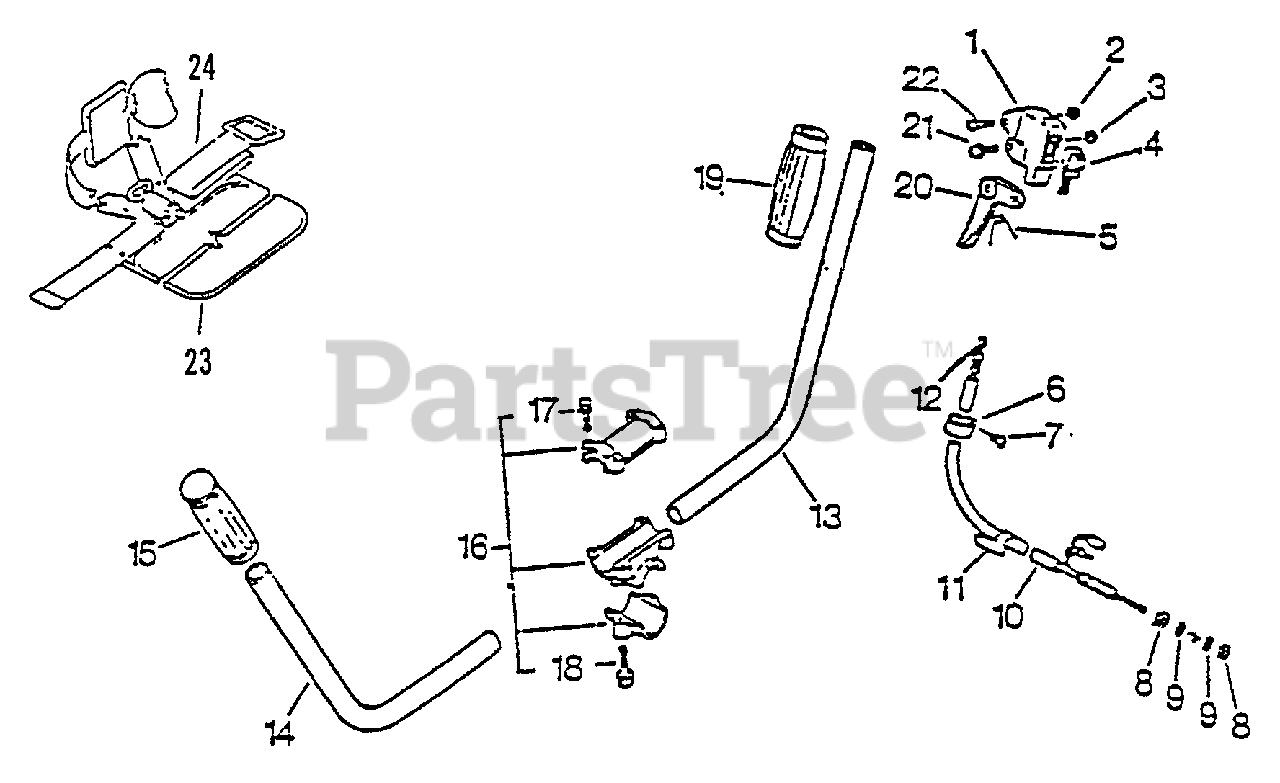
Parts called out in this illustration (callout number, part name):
1	BRACKET, THROTTLE
2	LOCKNUT - 5
4	IGNITION SWITCH ASSY
5	SPRING, TRIGGER
7	SCREW - 5X10
8	LOCKNUT - 6
9	WASHER - 6
10	TUBE - VINYL
12	CABLE, THROTTLE
14	HANDLE, FRONT - LEFT
15	GRIP, HANDLE - LEFT
16	HANDLE BRACKET KIT
17	BOLT - 5X25
18	BOLT - 6X30
19	GRIP, HANDLE
20	TRIGGER, THROTTLE
21	SCREW - 5X25
22	SCREW - 5X30
23	CUSHION
24	SHOULDER STRAP ASSY
